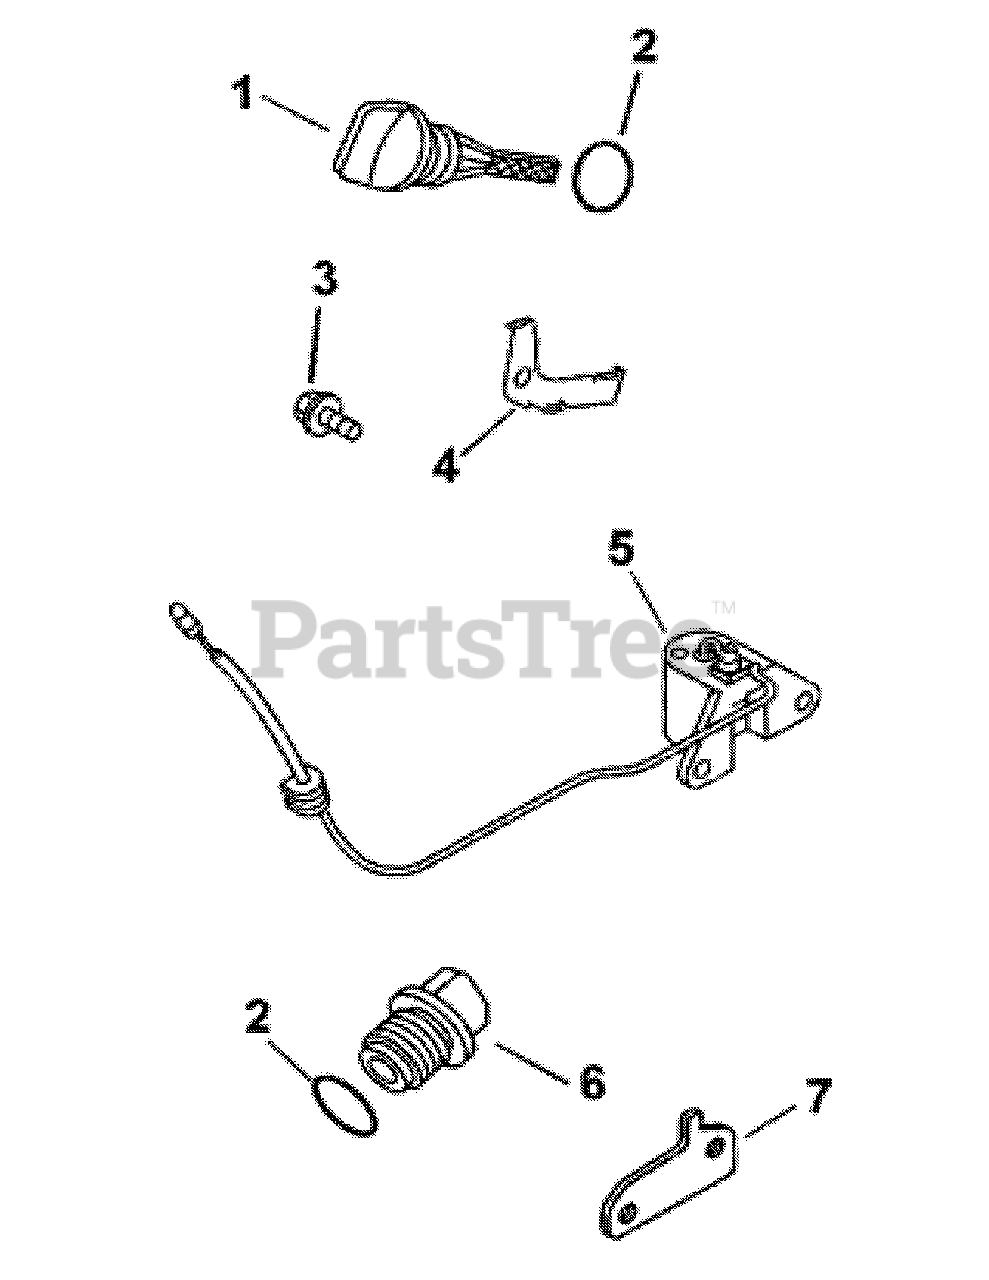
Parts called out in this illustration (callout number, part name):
1	Oil level Plug
2	Oil Plug O-Ring
5	Oil Pressure Switch
7	Oil Pressure Switch Spacer
